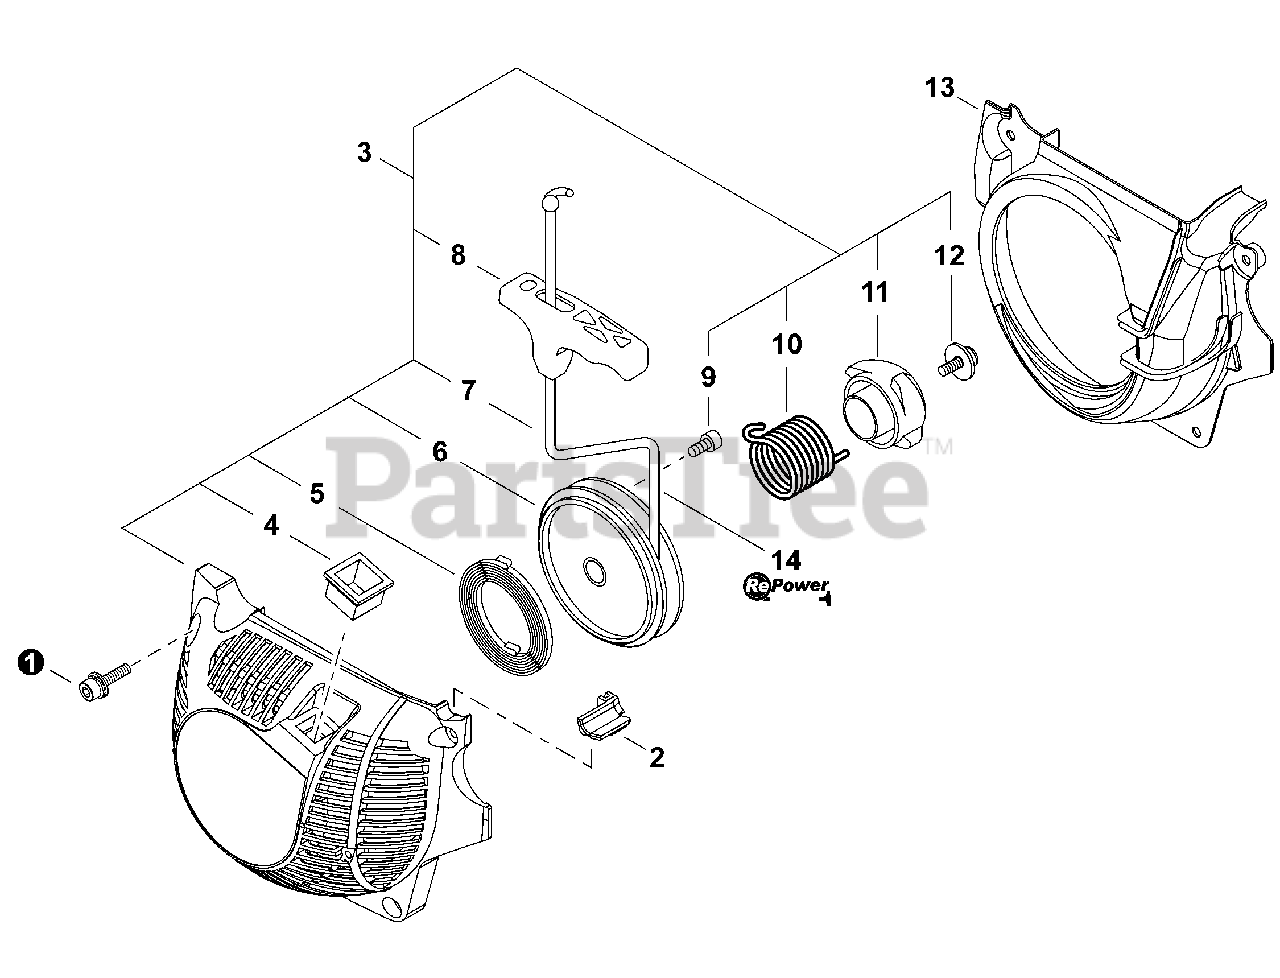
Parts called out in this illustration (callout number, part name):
1	BOLT M4×16
2	GROMMET, NEEDLE
3	STARTER ASSY
4	GUIDE, ROPE
5	SPRING, RECOIL
6	REEL, ROPE
7	ROPE, STARTER Ø3.8×750
8	GRIP, STARTER
9	BOLT 4×10
10	SPRING, TORSION
11	PAWL CATCHER
12	SCREW 5
13	COVER, FAN
14	BULK STARTER ROPE - Ø 3.5 MM×61 M
